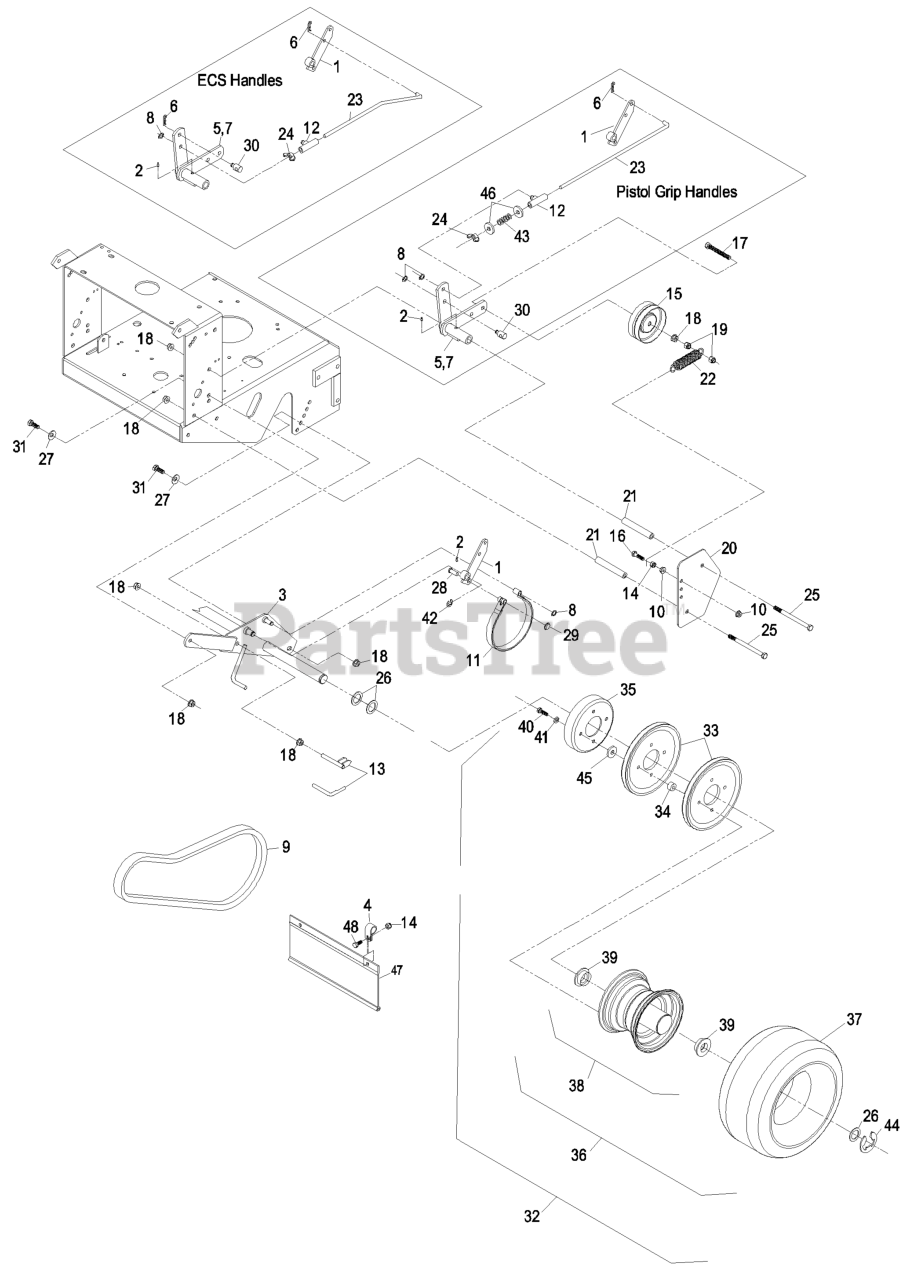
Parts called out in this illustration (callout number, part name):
1	ARM-BRAKE
2	FITTING-GREASE
4	CLAMP-R
6	PIN-COTTER
8	RING-RETAINING
9	BELT,WHEEL DRIVE
11	BAND-BRAKE
13	SCRAPER
14	NUT-LOCK, NI
15	IDLER-WHEEL, DRIVE
16	SCREW-HH
17	SCREW-HH
18	NUT-HHF, WHIZ
19	NUT-LOCK, NI
20	SHIELD-WHEEL, DRIVE
21	SPACER-SHIELD
22	SPRING-EXTENSION
23	LINKAGE-BRAKE
24	WINGNUT-NYLOCK
25	SCREW-HH
26	WASHER-SPACER
27	WASHER-BELLEVILLE
28	PIN-CLEVIS
29	RING-RETAIN,PUSH,EXT,FLAT
30	SWIVEL-LEVER, DRIVE
31	SCREW-HH
33	SHEAVE-WHEEL, DRIVE
34	SPACER-SHEAVE, WHEEL
35	DRUM-BRAKE
36	WHEEL AND TIRE ASM
37	TIRE-TURFMASTER
38	WHEEL AND HUB ASM
39	BEARING-FLANGED
40	SCREW-HH
41	WASHER-LOCK
42	RING-RETAINING, EXTERNAL
43	SPRING-COMPRESSION
44	RING-SNAP
46	WASHER-PLAIN
47	SHIELD-TRAILING
48	SCREW-HH
